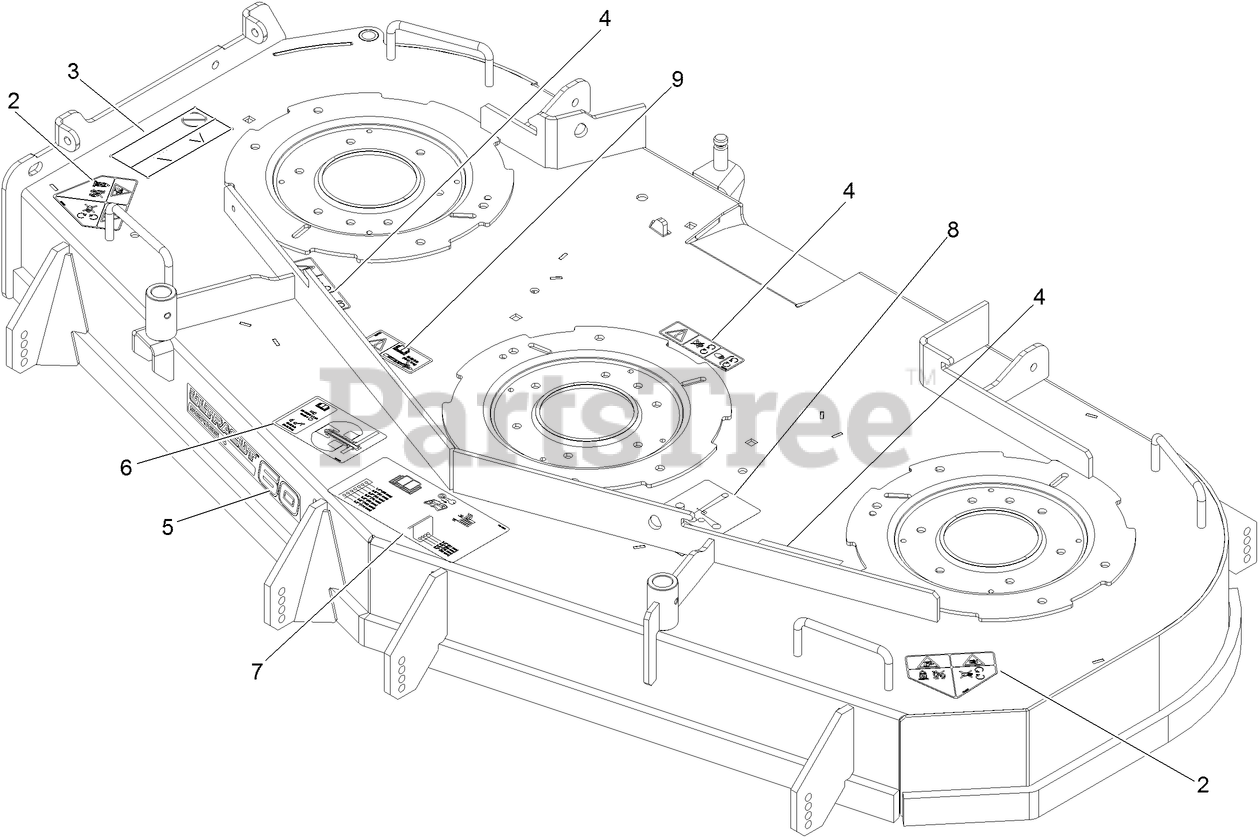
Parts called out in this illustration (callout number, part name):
2	DECAL-DANGER
3	DECAL-WARNING THROWN OBJ
4	DECAL-COVER, MISSING
5	DECAL, 604
6	DECAL-ROLLER MOUNTING
7	DECAL-ANTI-SCALP
8	DECAL-BELT ROUTING
9	DECAL-TORQUE, BOLT
